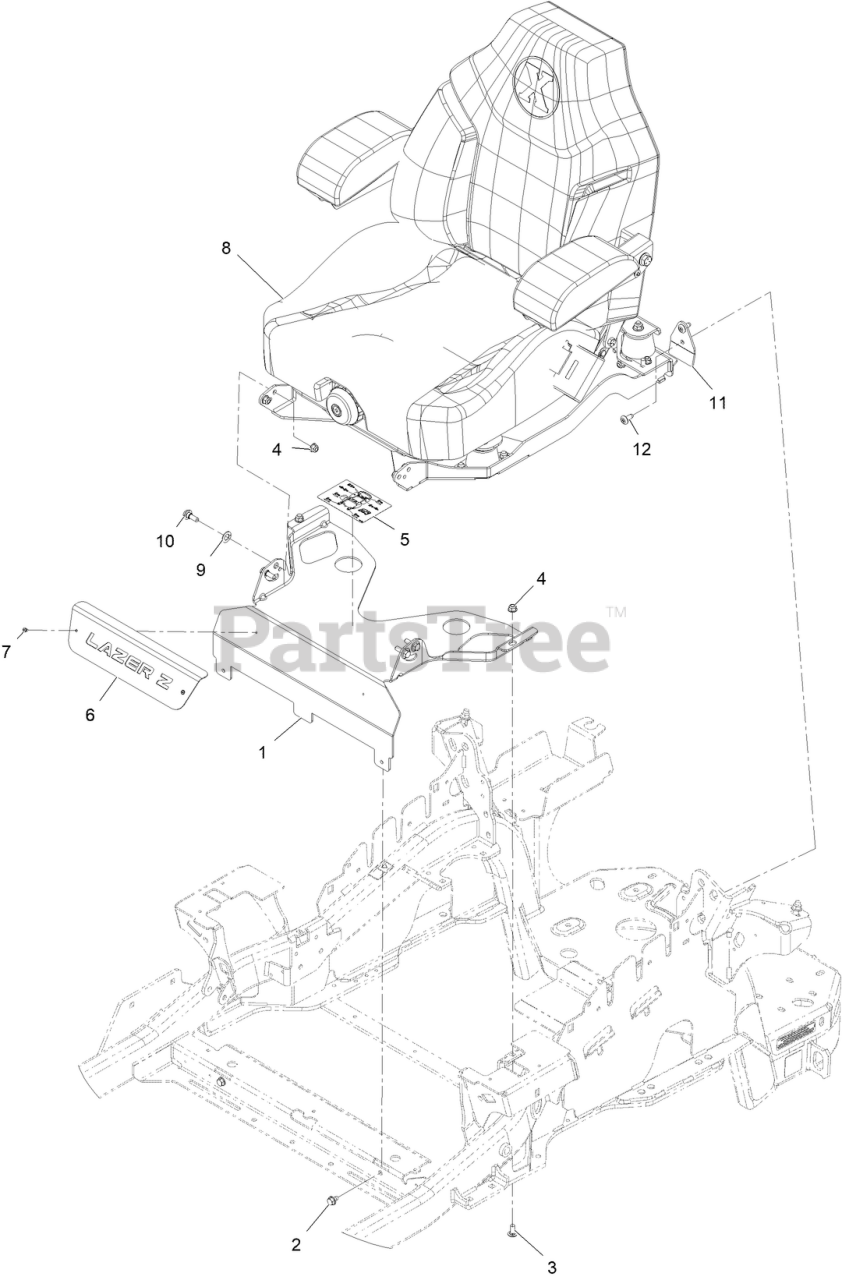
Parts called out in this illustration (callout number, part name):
1	SUPPORT-SEAT
3	SCREW-CARR
4	NUT-HF, NI
5	DECAL-SERVICE AID
6	PLATE-ACCENT HEEL
7	SCREW-PPH,SHEET METAL
8	ASM-Seat Suspension
9	WASHER-THRUST
10	SCREW-SHOULDER
11	LATCH-SEAT, UPPER
